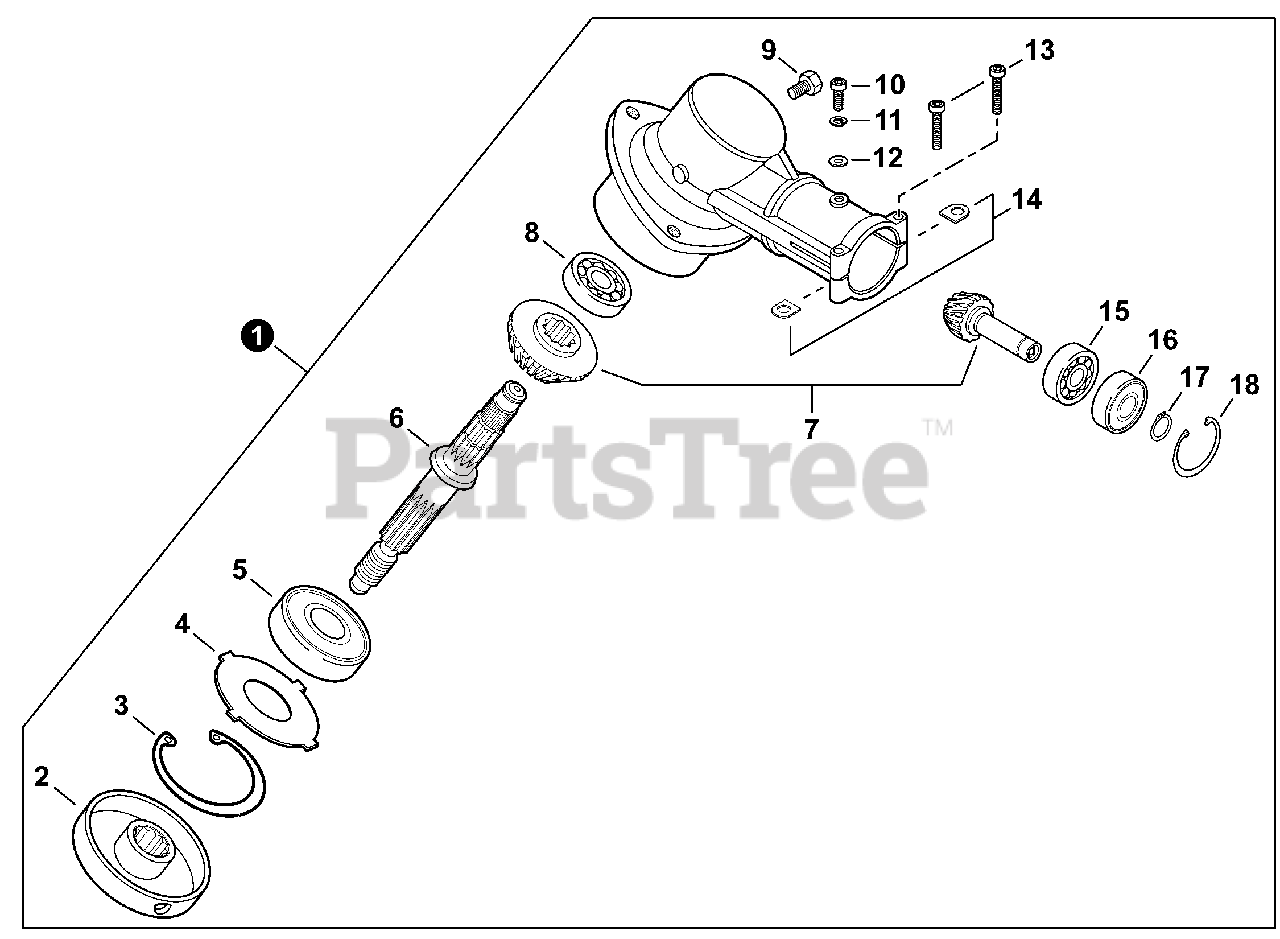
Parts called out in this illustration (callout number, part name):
1	GEAR CASE ASSY
2	PLATE, ADAPTOR - UPPER
3	RING, SNAP Ø32
5	BEARING, BALL 6201
6	SHAFT, GEAR
7	GEAR SET, BEVEL
8	BEARING, BALL 609
9	BOLT M8×8
10	BOLT, TORX 5×10
11	WASHER, SPRING 5
12	WASHER, FLAT 5.5×10×0.8
13	BOLT, TORX 5×25
14	D-WASHER
15	BEARING, BALL 6900
16	BEARING, BALL 6900-Z
17	RING, SNAP Ø10
18	RING, SNAP Ø22
